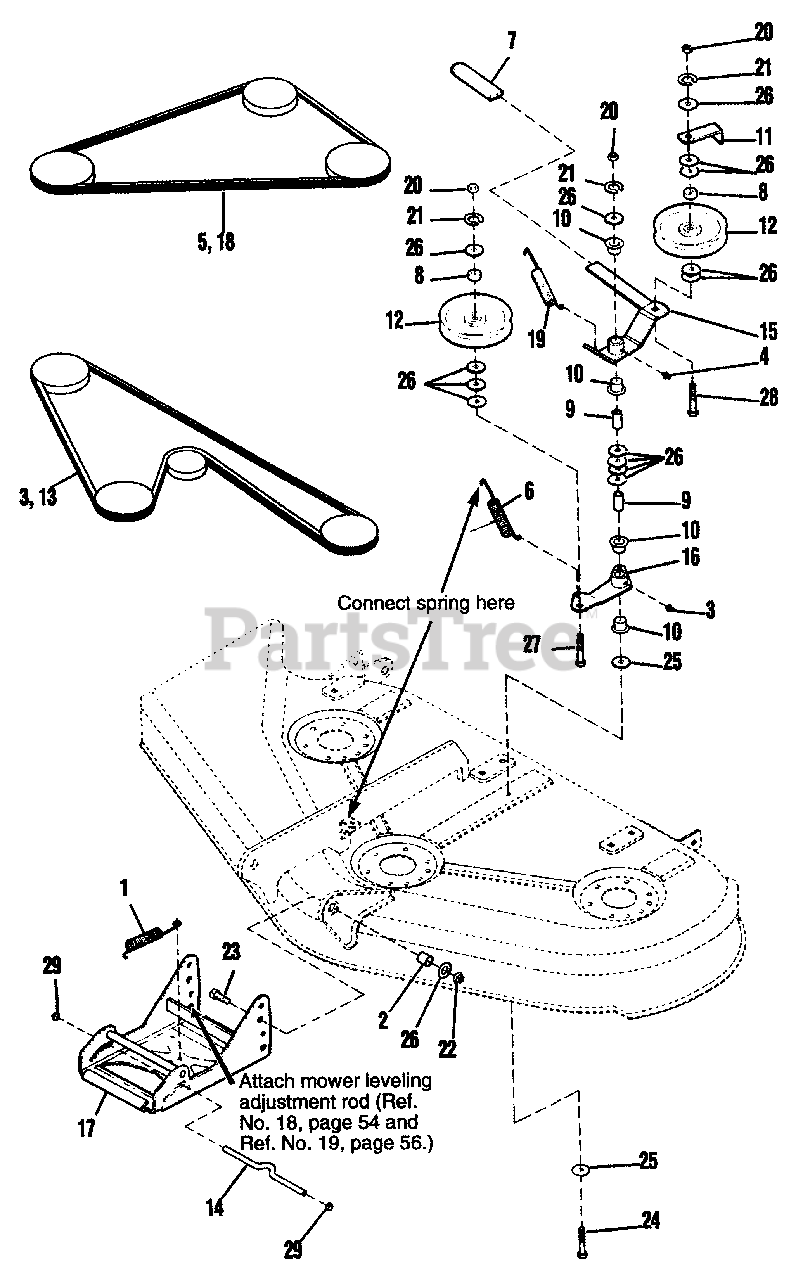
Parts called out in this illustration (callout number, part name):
3	V-BELT, Deck Drive (44")
4	GREASE FITTING
5	V-BELT, Mower Drive (44")
7	GRIP, Lever
11	IDLER, Stop
12	PULLEY ASSY.
13	V-BELT, Deck Drive (50")
15	LEVER ASSY, Idler (Incl. Qty 2, Ref. No. 10)
16	LEVER ASSY., Idler Arm (Incl. Qty 2, Ref. No. 10)
17	HITCH ASSY.
18	V-BELT, Mower Drive (50")
20	NUT, Hex, 3/8-16
21	LOCKWASHER, 3/8
22	NUT, Hex, Lock, 3/8-16
23	CAPSCREW, Hex Hd., 3/8-16 x 1-1/2
24	CAPSCREW, Hex Hd., 3/8-16 x 3-1/2
25	WASHER
26	WASHER, 5/16
27	CARRIAGE BOLT, 3/8-16 x 1-1/2
28	CARRIAGE BOLT, 3/8-16 x 1-3/4
29	NUT, Push On
